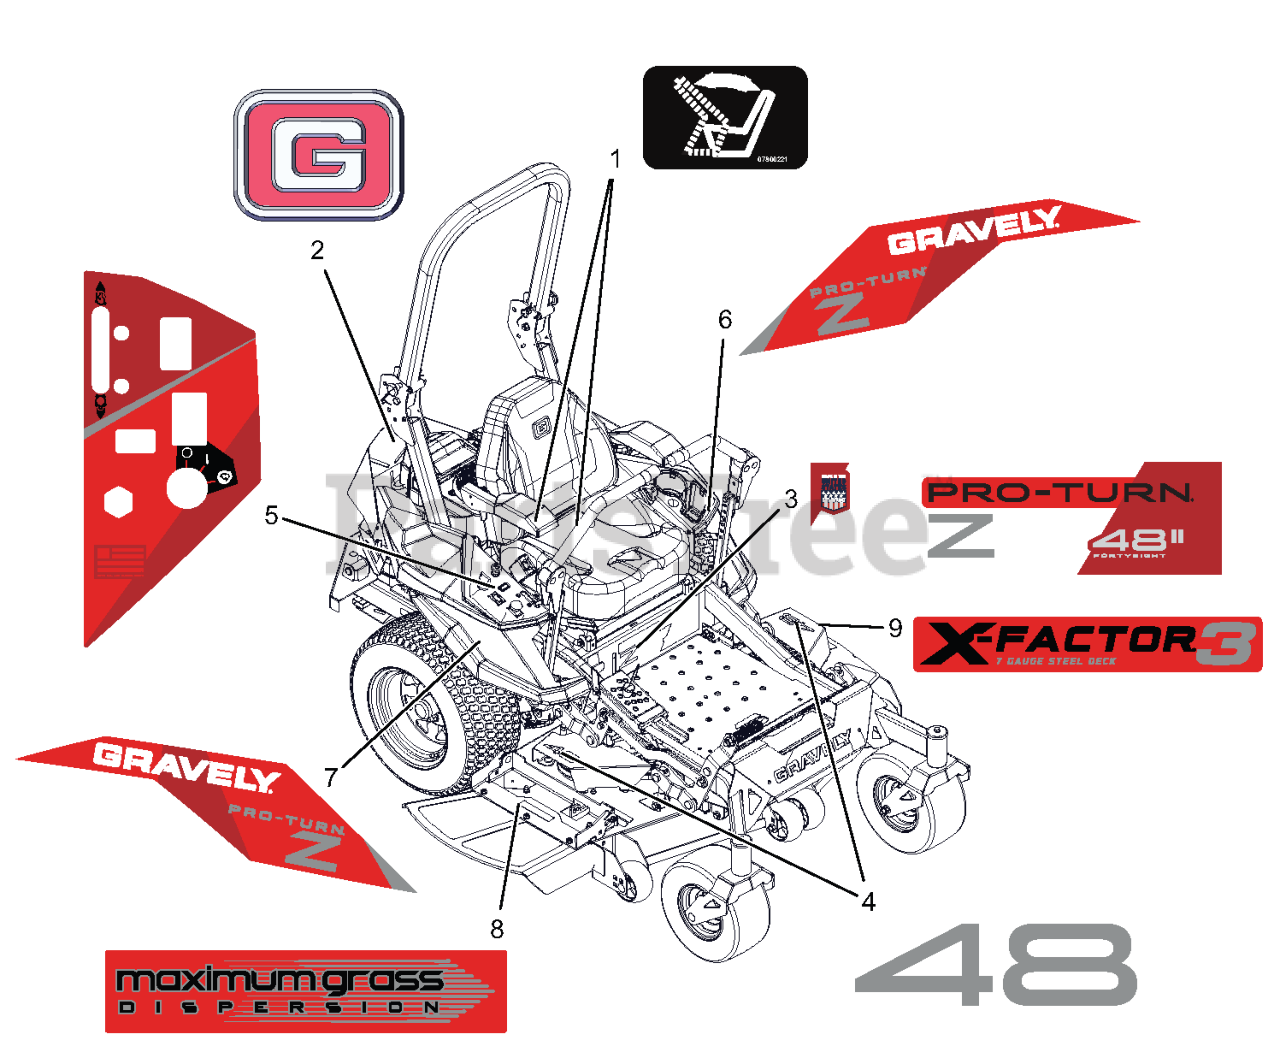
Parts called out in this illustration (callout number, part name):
1	DECAL - SEAT RELEASE
2	DECAL, GRAVELY BRAND
3	DECAL, PTZ - 48
4	DECAL, DECK - 48
5	DECAL, CONTROL PANEL
6	DECAL, FENDER LH - PTZ
7	DECAL, FENDER RH - PTZ
8	DECAL, DECK - MAX GRASS
9	DECAL, DECK - X-FACTOR 3 7 GAUGE
